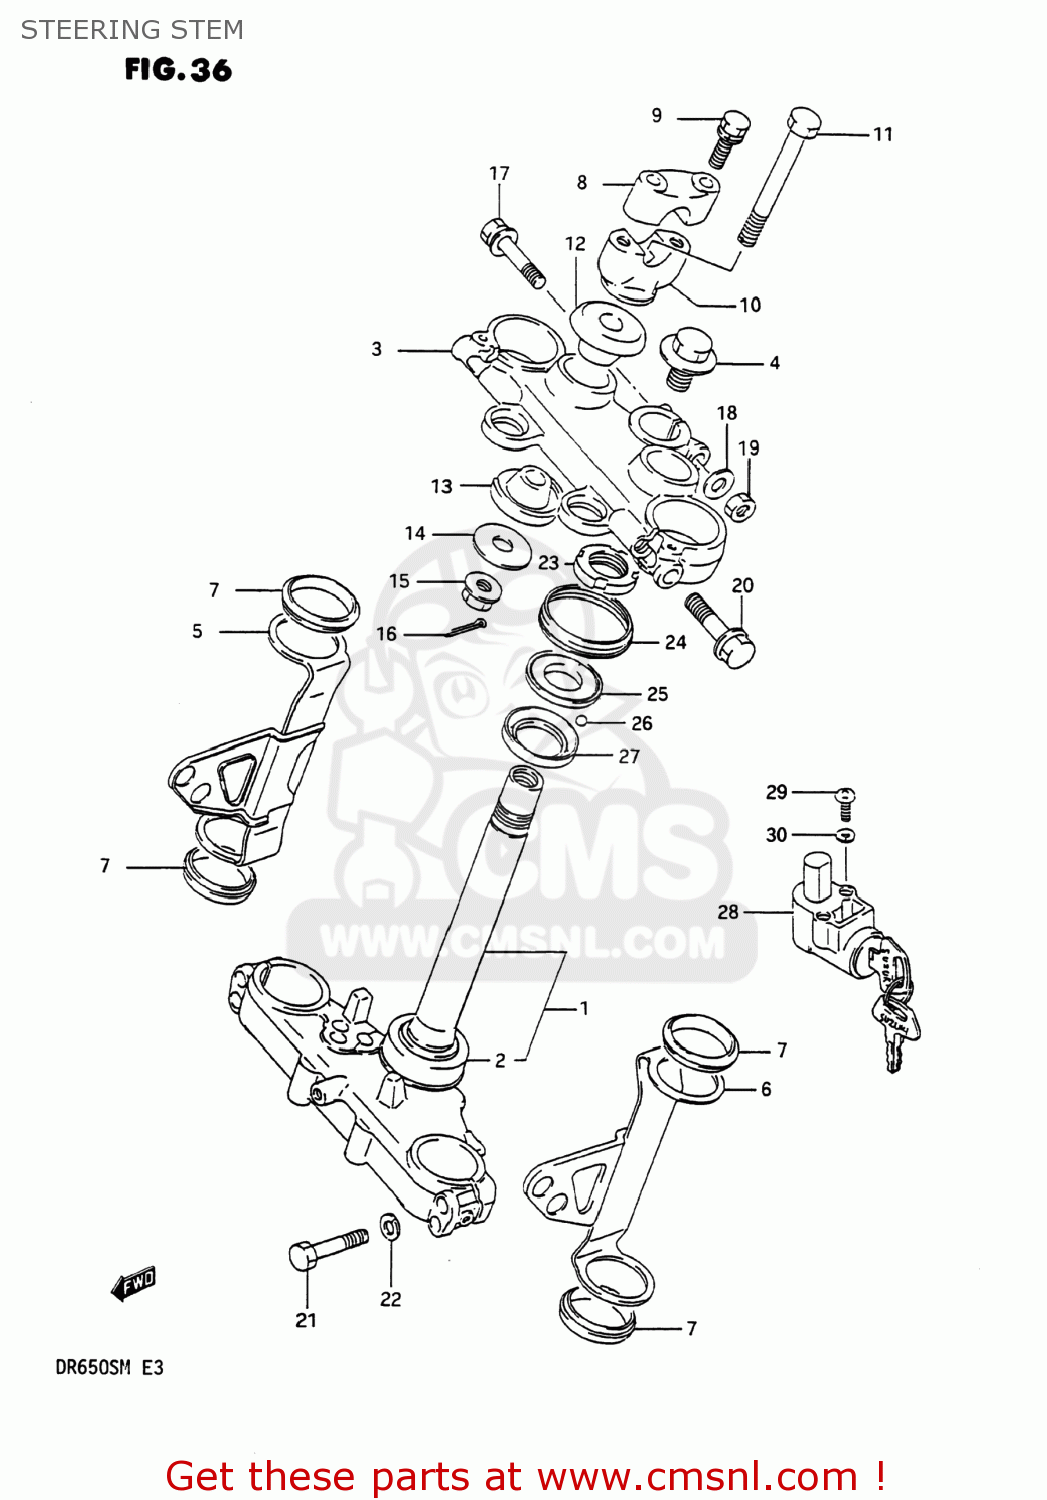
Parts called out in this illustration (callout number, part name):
1	STEM,STEERING
2	BEARING(30X55X17)
3	HEAD,STEERING STEM
4	BOLT,STEERING STEM
5	COVER,FORK,RIGHT
6	COVER,FORK,LEFT
7	CUSHION,HEADLAMP BRACKET
8	HOLDER,HANDLEBAR
9	BOLT
10	HOLDER,HANDLE LWR
11	BOLT,HANDLE HOLDER
12	DAMPER,UPR
13	DAMPER,LWR
14	WASHER,HANDLEBAR HOLDER
15	NUT
16	COTTER PIN
17	BOLT
18	WASHER
19	NUT ,8MM
20	BOLT
21	BOLT
22	LOCK WASHER
23	NUT,STEERING STEM
24	SEAL,STEERING UPR DUST
25	RACE,STEERING,OUTER,UPPER
26	BALL
27	RACE,STEERING INNER (SUJ)
28	LOCK ASSY,STEERING
29	SCREW
30	LOCK WASHER
